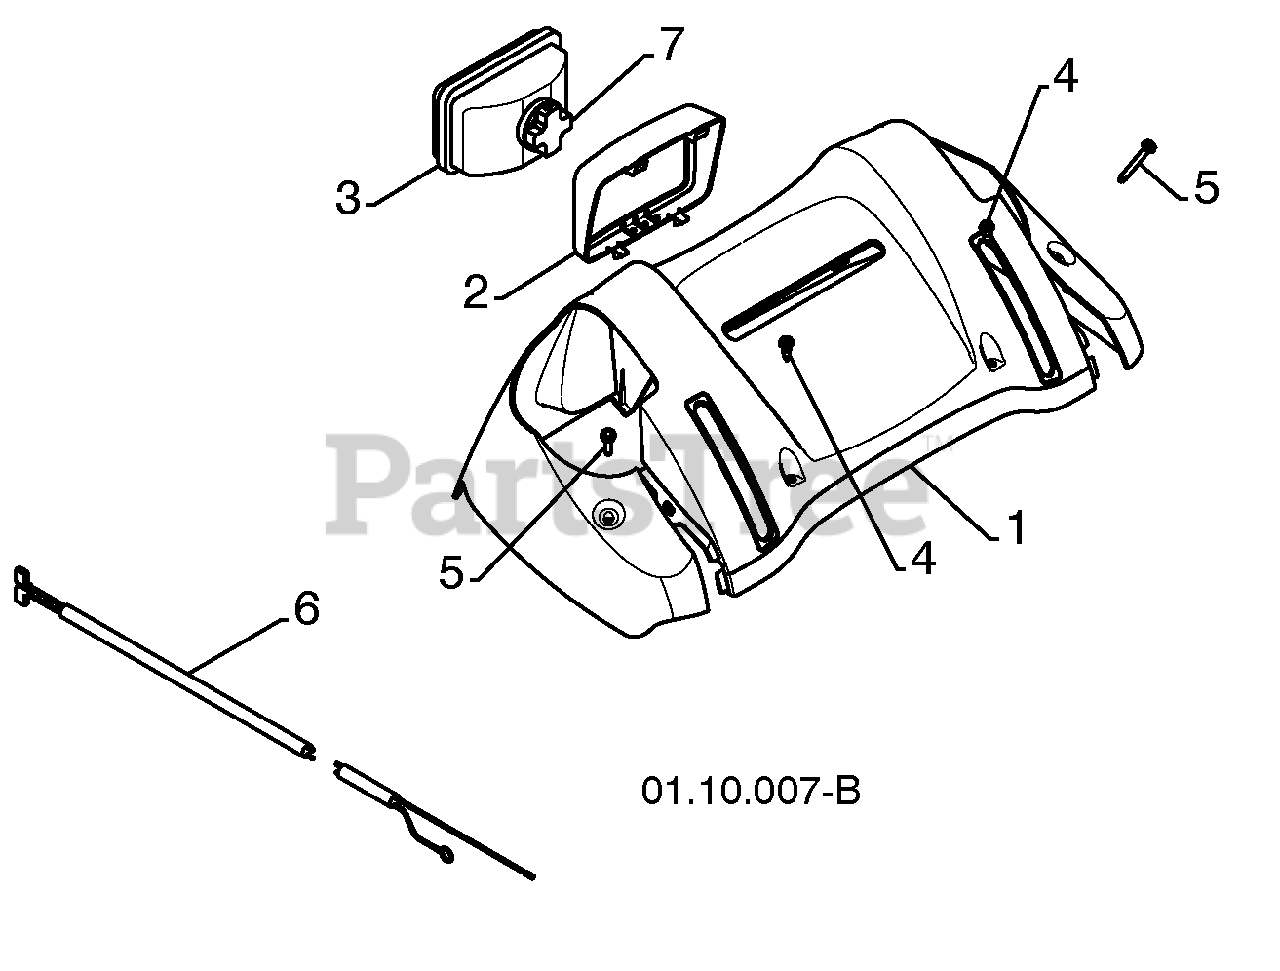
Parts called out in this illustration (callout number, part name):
1	CONSOLE PANEL
2	HEADLIGHT BEZEL
3	FLOOD HEADLIGHT
4	SHOULDER SCREW 10-24 X .625
5	SCREW 10-24 X 1.25
6	WIRE HARNESS
7	BULB
